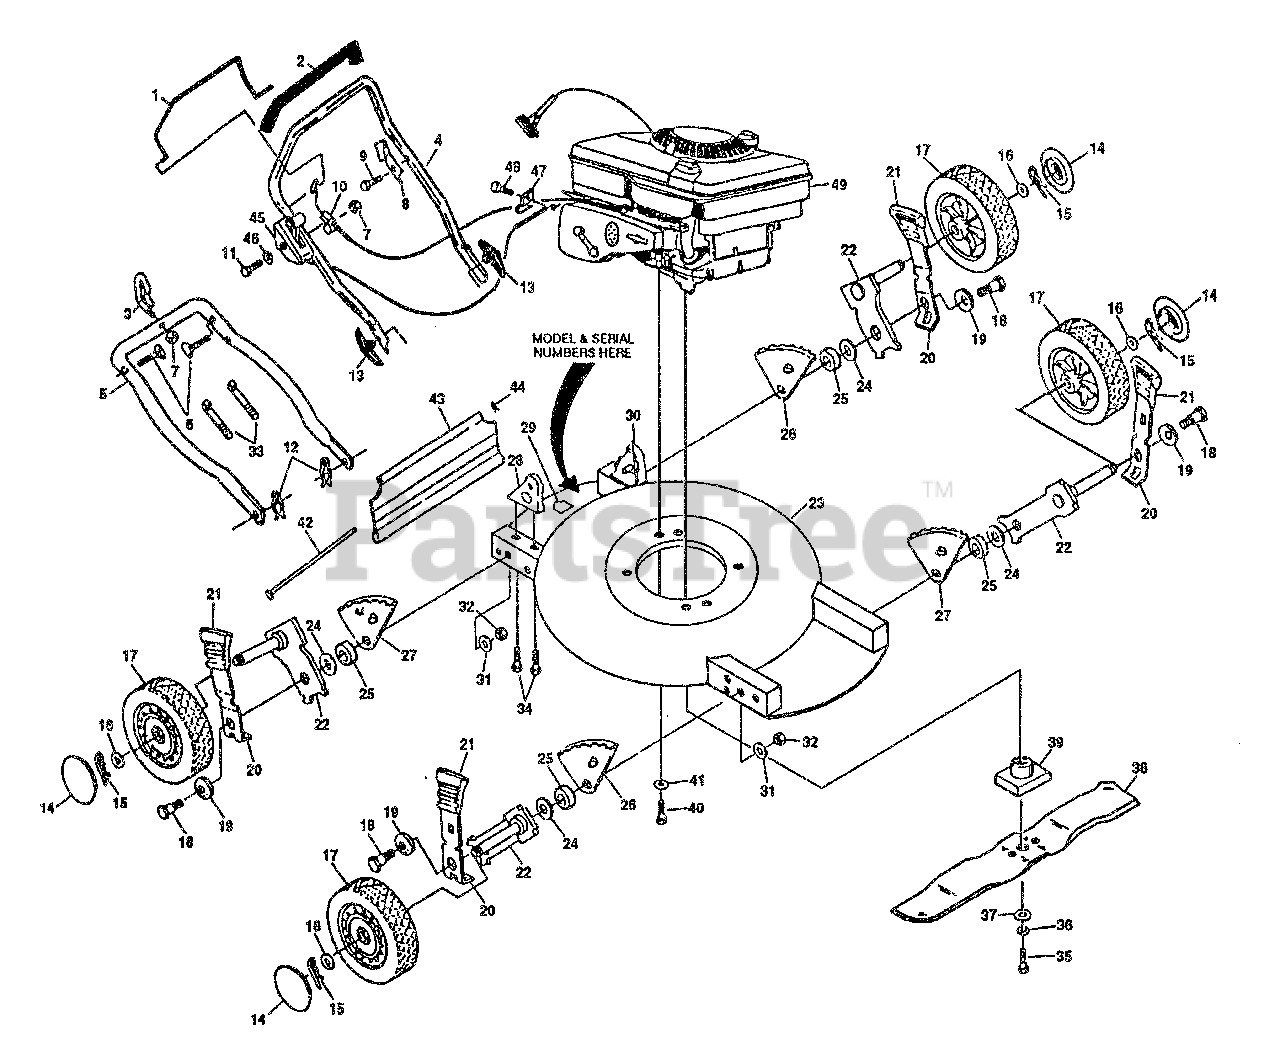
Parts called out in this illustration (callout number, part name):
1	Control Bar
2	Handle Grip
3	Rope Guide
4	Upper Handle - 84676x418 Gray
5	Lower Handle - 84676x479 Blk
6	Handle Bolt 5/16-18 x 1-3/4
7	Lockout 1/4-20
8	Up-Stop Bracket
9	Hex Washer Head Screw #10-24 x 1/2
10	Engine Zone Control Cable
11	Pan Head Screw 1/4-20 x 2-1/8
12	Hairpin Cotter
13	Handle Knob
15	Retainer Clip
16	Washer
17	Wheel & Tire Assembly 8.0 x 2.0
18	Shoulder Bolt
19	Belleville Washer
20	Selector Spring
21	Selector Knob
22	Axle Arm Assembly
23	Lawn Mower Housing
25	Spacer
26	Wheel Adjusting Bracket (R.F./L.R.)
27	Wheel Adjusting Bracket (L.F./R.R.)
28	Handle Bracket Assembly (Right)
29	Danger Decal
30	Handle Bracket Assembly (Left)
31	Washer
32	Lockout 3/8-16
33	Wire Tie
34	Thread Cutting Screw 5/16-18 x 3/4
35	Hex Head Screw 3/8-24 x 1-3/8
36	Helical Lockwasher 3/8
37	Hardened Washer
38	20" Blade
39	Blade Adapter
40	Hex Head Thread Rolling Screw 3/8-16 x 1-1/8
42	Deflector Rod
43	Rear Deflector
44	Retainer Clip
45	Throttle Control
47	Cable Clamp
48	Thread Rolling Screw #10-32 x 5/8
